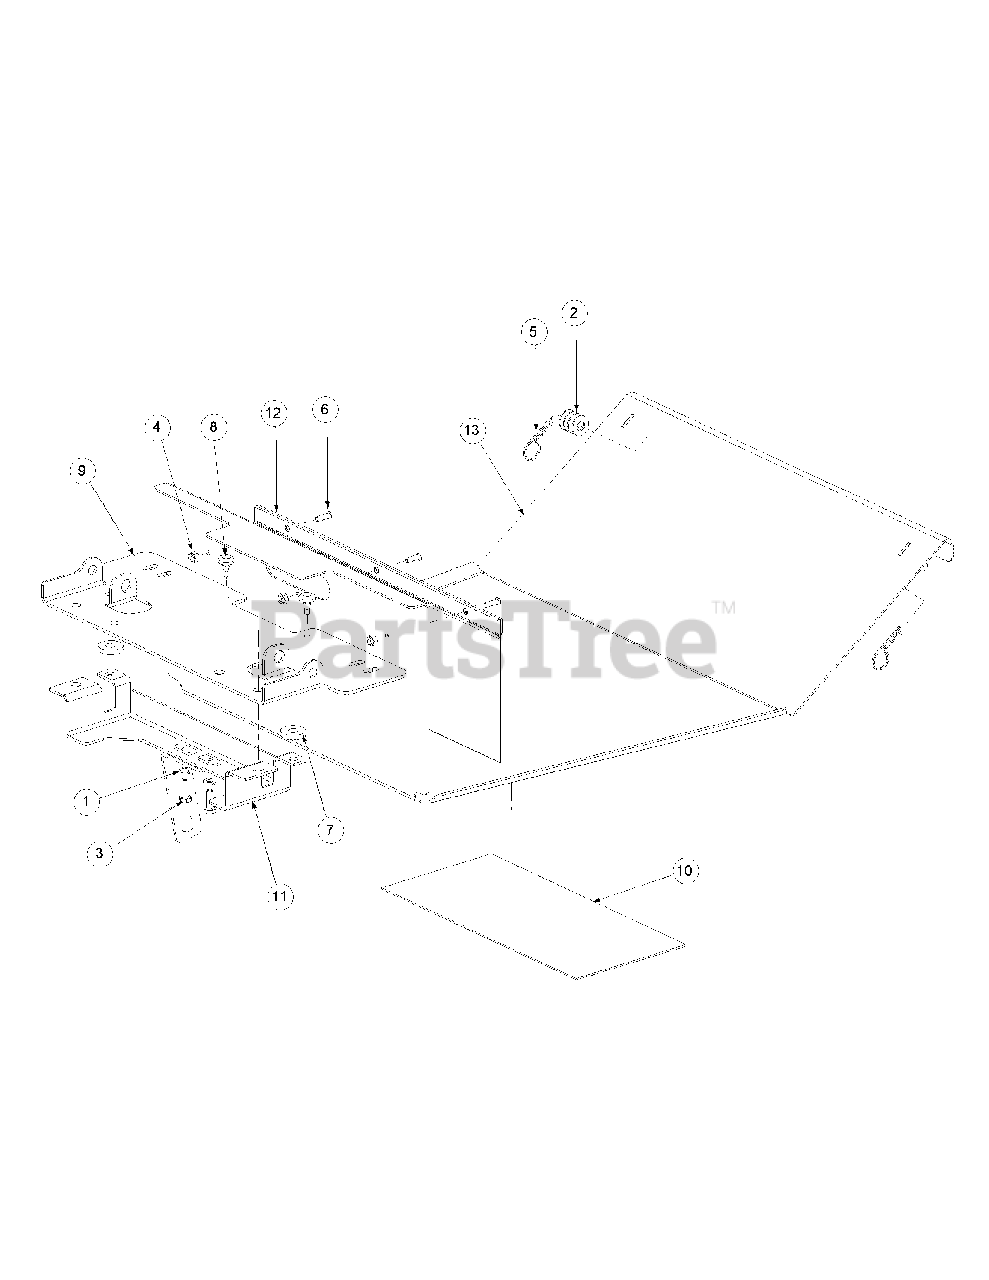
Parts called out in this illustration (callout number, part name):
1	Lock Washer, 1/4
2	Washer
3	Hex Cap Screw, 1/4-20, .75
4	Lock Nut, Nylon Insert, 10-32
5	Hair Pin, 3/8-1/2
6	Screw, Phillips Head, Machine, 10-32 x 5/8
7	Washer
8	Rubber Bumper, .62 OD x .22 Thick
10	Label, Belt Routing and Lubrication
11	Support, Seat Bracket
12	Bag, Debris Storage
13	Floor Panel Assembly
